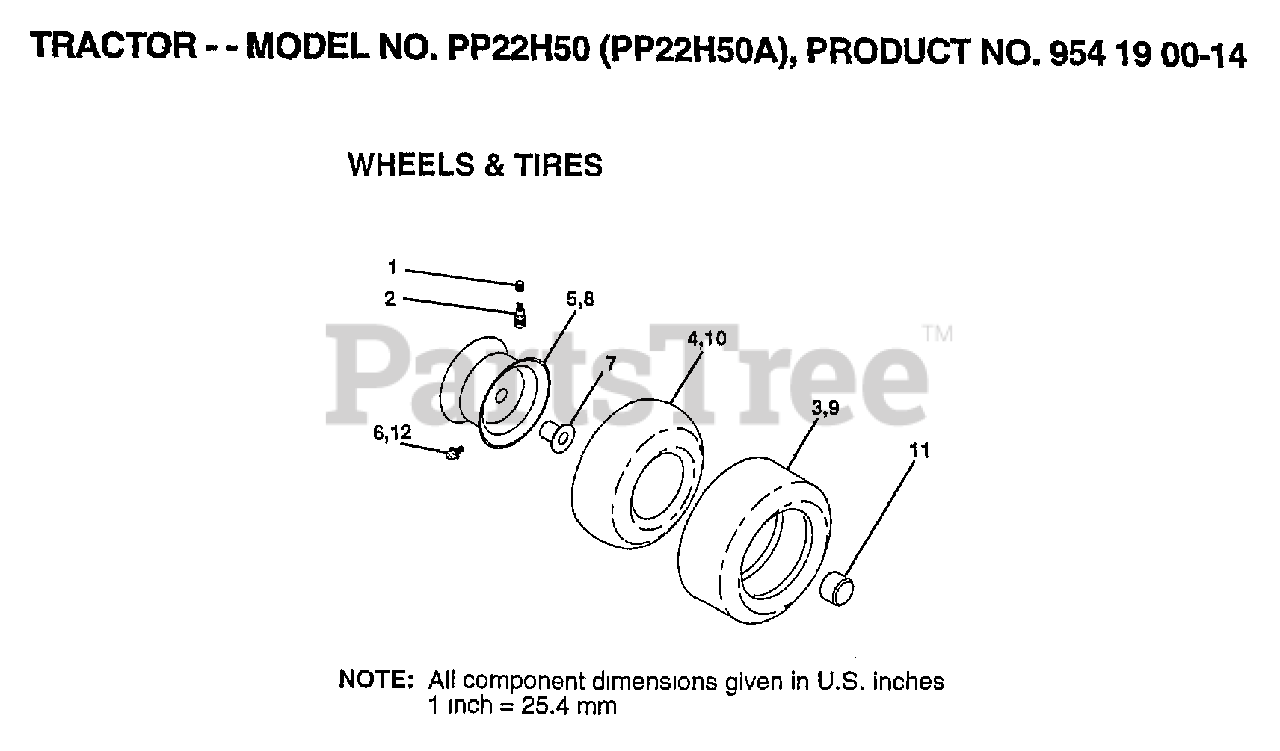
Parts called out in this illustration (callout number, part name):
1	VALVE CAP
2	VALVE STEM LT
4	TUBE.16X6.5/7.5-8
5	RIM.FRONT.
6	ZERK FITTING M
7	"FLANGE, BEARING"
8	"WHEEL,REAR"
10	TUBE.23X8/10-12
11	HUB CAP
12	FITTING LT
